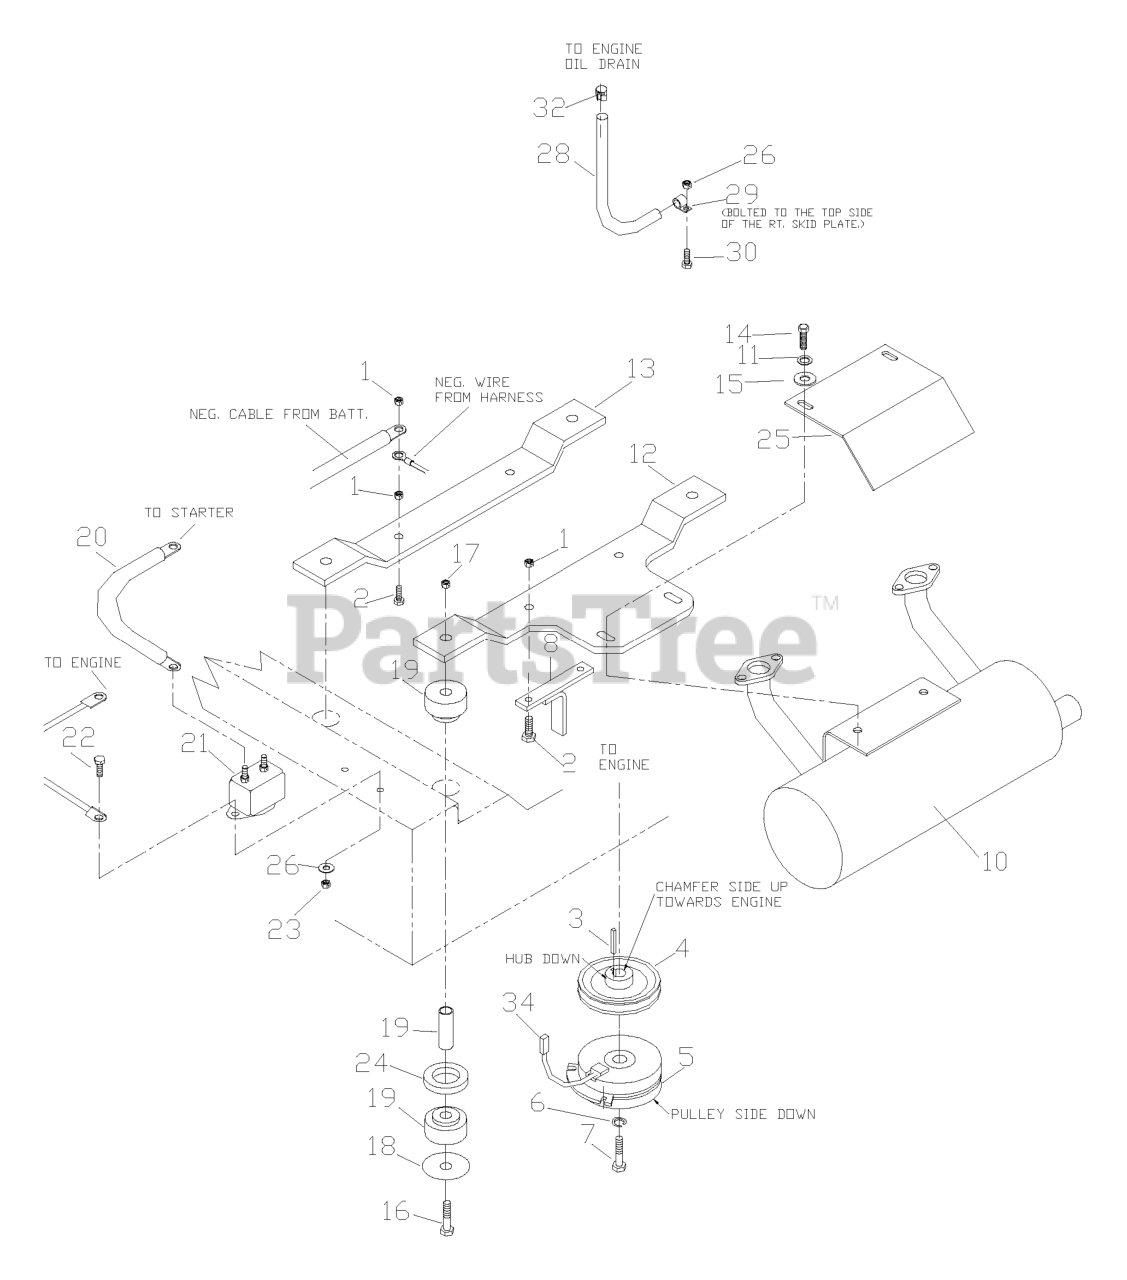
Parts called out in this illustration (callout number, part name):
1	NUT 5/16C CENTERLOCK
2	HCS 5/16C X 1 3/4
3	KEY 1/4" SQ X 1 7/8"
5	ELECTRIC CLUTCH W/CABLE
6	WASHER 7/16 LOCK
7	BOLT 7/16F X 2 1/2
8	CLUTCH TIE DOWN
9	KAW PIGTAIL
10	MUFFLER KAWASAKI GEN II
11	WASHER.LOCK.HVY.HLCL.SPR.5/16
12	REAR ENGINE MOUNT
13	ENGINE MOUNT
14	HCS 5/16C X 3/4
15	WASHER 5/16 FLAT
16	HCS 1/2C X 3 1/4
17	NUT 1/2-13 HEX NYLOC ZD
18	ISOLATOR WASHER
20	CABLE POSITIVE
22	HCS 1/4C X 5/8
23	NUT 1/4C CENTER LOCK
24	ISOLATOR SPACER
25	MUFFLER GUARD
26	WASHER 1/4 INT TOOTH
27	GROUND WIRE (KAW)
28	OIL DRAIN HOSE (KAW)
30	HCS 1/4C X 3/4 HCS
31	CHOKE CONTROL, COMPLETE
34	CLUTCH HARNESS
